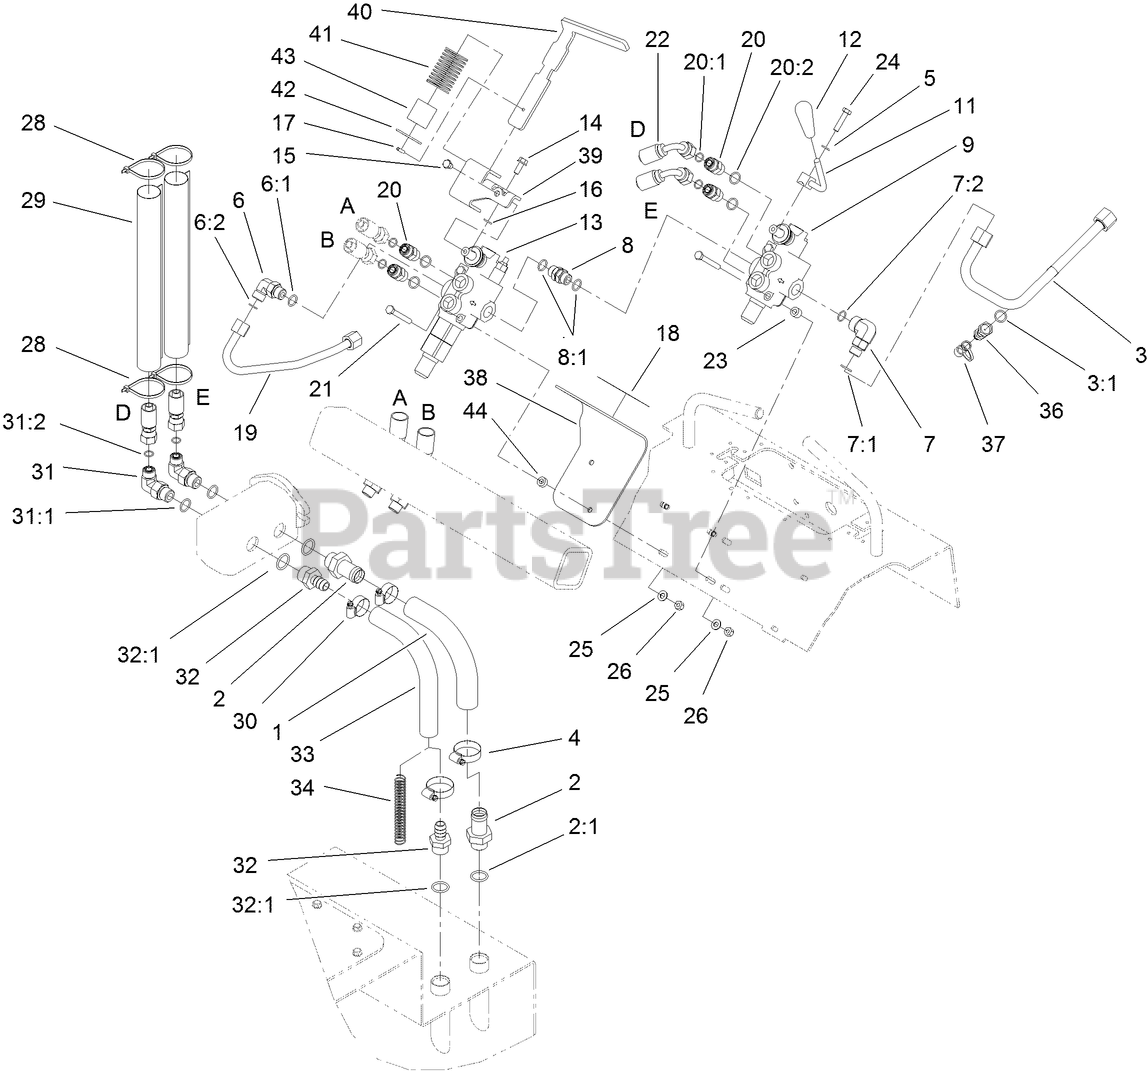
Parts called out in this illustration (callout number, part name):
1	HOSE-SUCTION, FORMED
2	FITTING
2:1	O-RING
3	HYD TUBE ASM
3:1	O-RING
5	WASHER-LOCK
6	FITTING-ELBOW-90 DEG
6:1	O-RING
6:2	O-RING
7	Fitting-Elbow, 90 DEG
7:1	O-RING
7:2	O-RING
8	FITTING-THREAD, STRAIGHT
8:1	O-RING
9	VALVE-SELECTOR, HYD
11	LEVER-CONTROL
12	KNOB-TAPERED
13	VALVE-HYD, AUXILIARY
14	SCREW-HHF
15	SCREW-HH
16	WASHER-LOCK
17	PIN-SPRING
18	DECAL-AUXILIARY
19	TUBE-HYD
20	FITTING-STRAIGHT
20:1	O-RING
20:2	O-RING
21	SCREW-HH
22	HOSE-HYD
23	SPACER
24	SCREW-HH
25	WASHER-PLAIN
26	NUT-LOCK, NI
28	TIE-CABLE
29	SLEEVE-THERMAL
30	CLAMP-HOSE
31	FITTING-ELBOW 90
31:1	O-RING
31:2	O-RING
32	FITTING-STRAIGHT
32:1	O-RING
33	HOSE-SUCTION, HYD
34	Spring-Compression
36	NIPPLE-TEST
37	CAP-DUST
38	BRACKET-AUXILIARY
39	MOUNT-LEVER, AUXILIARY
40	HANDLE-LEVER, AUXILIARY
41	SPRING
42	RETAINER-SPRING, AUXILIARY
43	TUBE-SPRING
44	SPACER
